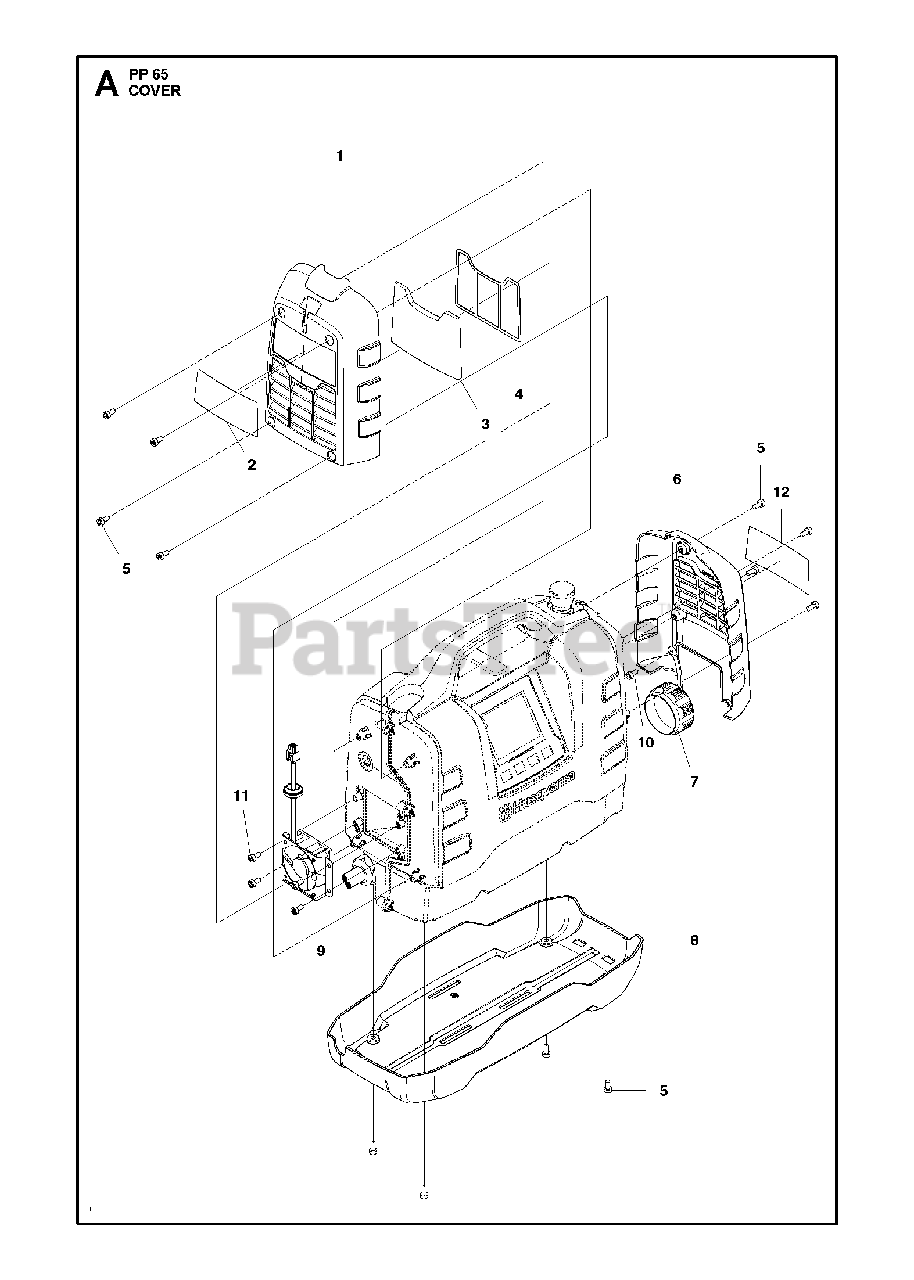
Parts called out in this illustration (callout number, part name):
6	COVERIncl decal, NA & AUS only
10	SCREW ITXSCT
11	SCREW CRPANT
